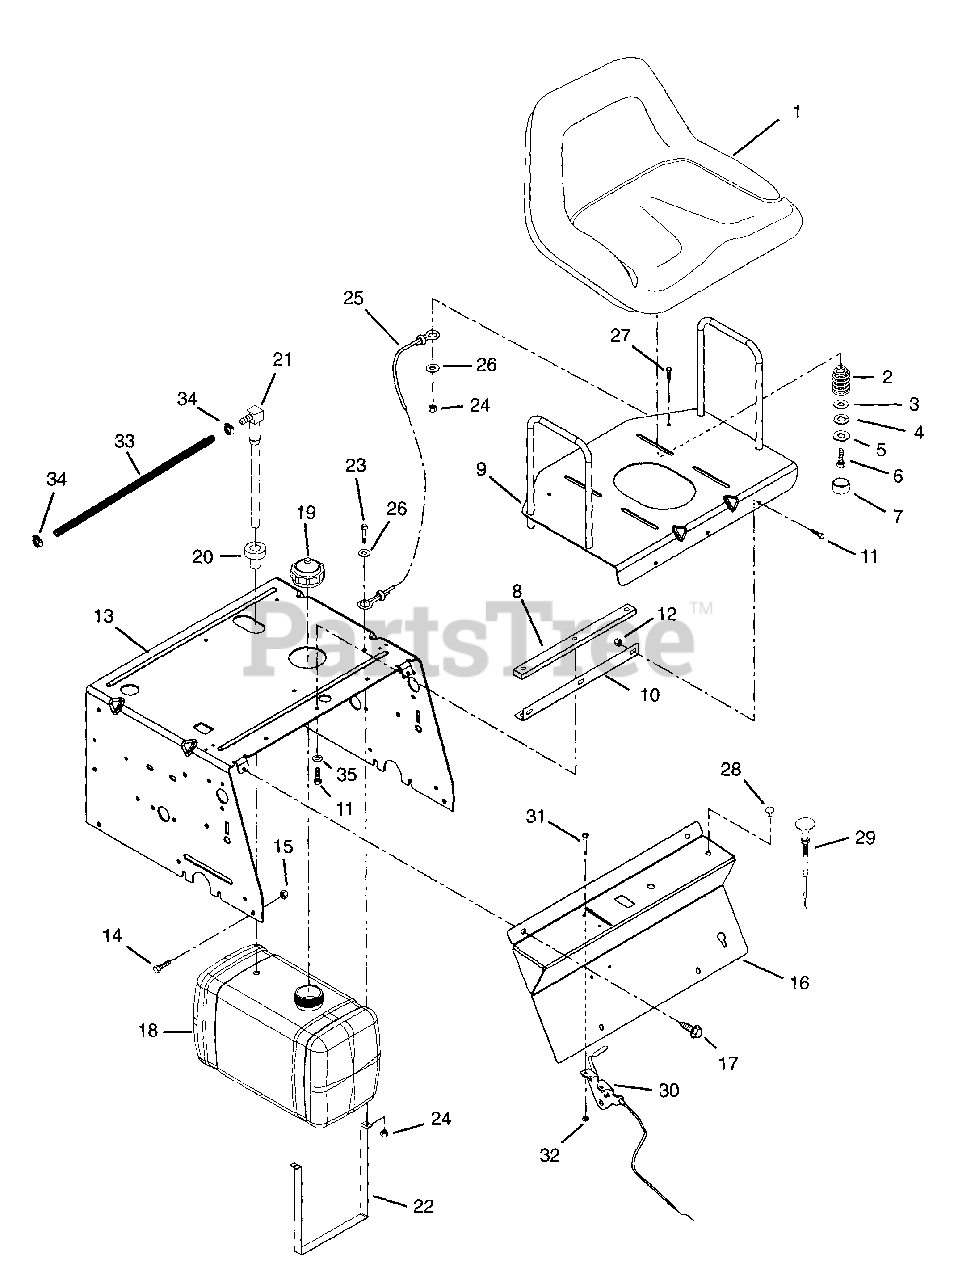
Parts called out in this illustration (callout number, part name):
2	SG-COMP .148X1.23X2.41 WLD87
3	WSHR-FL-STL.344X.688X.065PL
4	WSHR-LK .313X.078 PL MED
5	WSHR-FL-STL .380X.875X.179 PL
6	BLT-HEX .31-18X1.00 PL GR5
7	TUBE CAP
8	PLT,CLAMPING
9	SEAT PLATE WELDMENT
10	HINGE-2" X 12.88 YWZC
11	BLT-HEX .31-18X.75 PL GR5
12	NUT-LK-NYL.312-18 PL
13	SEAT SUPPORT
14	BLT-HEX .38-16X1.00 PL GR5
15	NUT-LK-CTR .375-16 GR A PL
16	CONTROL PANEL
17	SCR-TAP .312-18X.50 HWH PL TR
18	FUEL TANK
19	FUEL CAP
20	BSHG-FLG .375 X 1.062 X .625 R
21	FITTING, TANK
22	STRP,FUEL TANK
23	BLT-HEX .25-20X2.00 FLLTHD GR5
24	NUT-LK-NYL .250-20 PL
26	WSHR-FL-STL .328X1.0X.094 PL
27	BLT-HEX .25-20X.75 PL GR5
28	HOLE PLUG, PLASTIC .44 HOLE
29	CONTROL,CHOKE
30	CABLE THROTTLE - EZR 14 + 15HP
31	SCR-MCH 10-24X.50 PHD
32	NUT-LK 10-24 NY PL
33	HOSE, FUEL .25 ID X 22 LG
34	CLAMP-HOSE WIRE .490/.510X.116
35	WSHR-LK .312X.097 PL HVY
